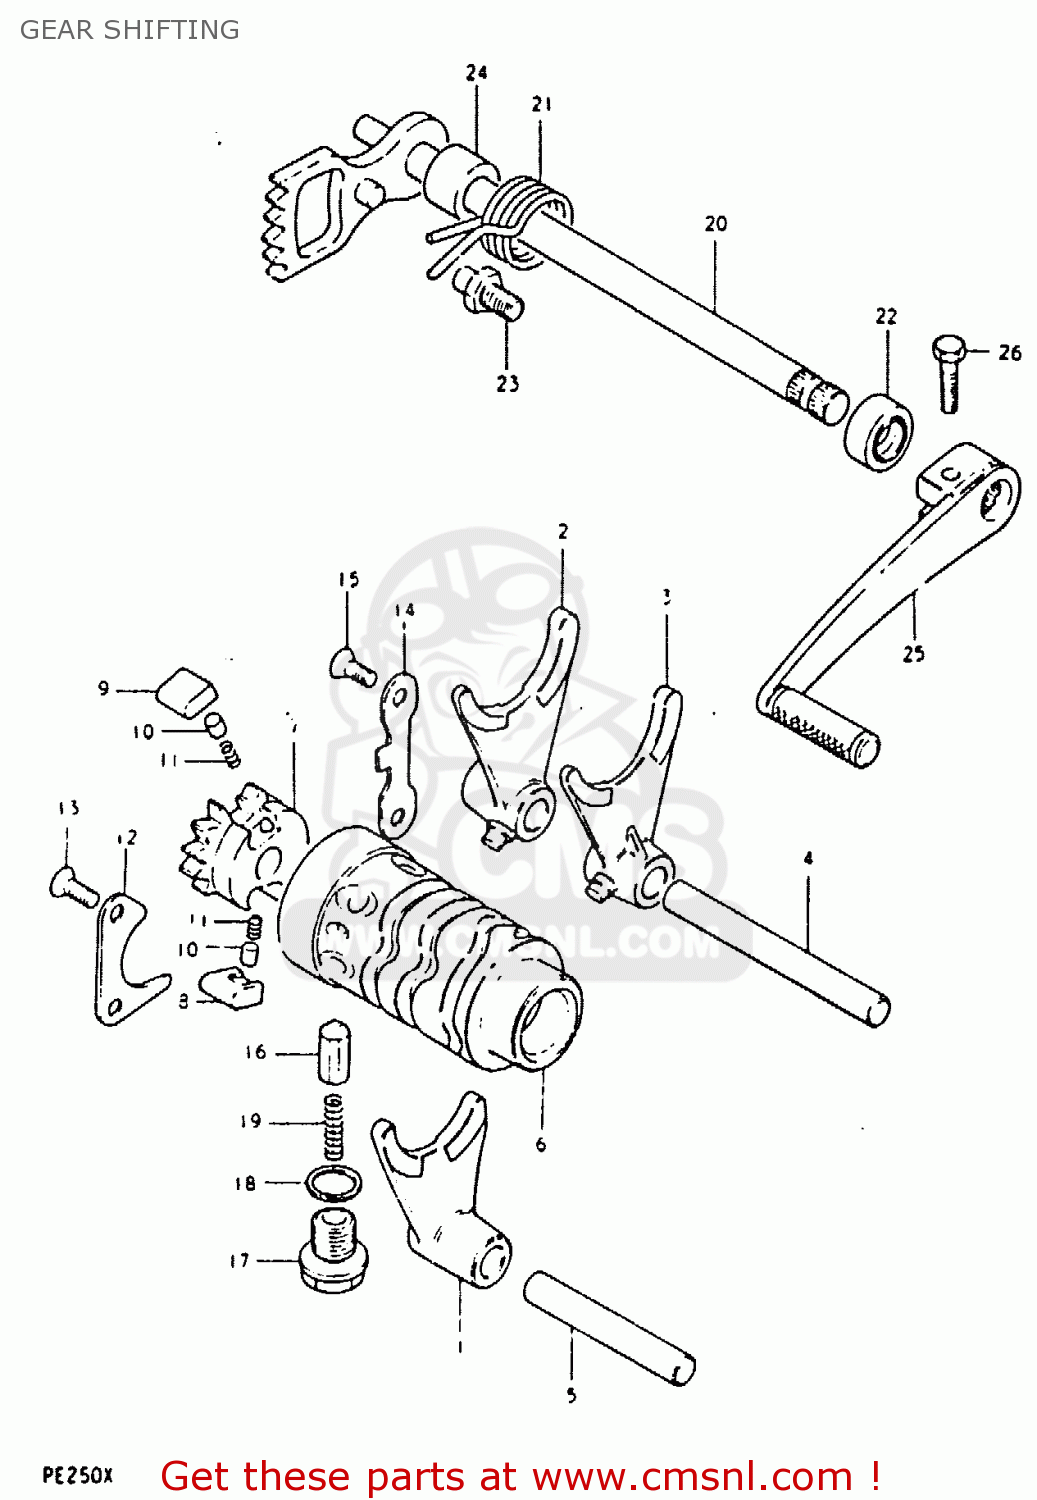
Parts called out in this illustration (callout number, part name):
1	FORK,GEAR SHIFT NO.1
2	FORK,GEAR SHIFT NO.2
3	FORK,GEAR SHIFT NO.3
4	SHAFT,GEAR SHIFT FORK
5	SHAFT,GEAR SHIFT FORK
6	CAM,GEAR SHIFT
7	RETAINER,GEAR SHIFT CAM
8	PAWL,GEAR SHIFT NO.1
9	PAWL,GEAR SHIFT NO.2
10	PIN(5X8)
11	SPRING
12	LIFTER,GEAR SHIFT PAWL
13	SCREW
14	GUIDE,GEAR SHIFT CAM
15	SCREW
16	STOPPER,GEAR SHIFTING
17	BOLT,GEAR SHAFT CAM STOPPER
18	GASKET(14X19.2X2) (NAS)
19	SPRING
20	SHAFT,GEAR SHIFT
21	SPRING
22	OIL SEAL
23	STOPPER,GEAR SHIFT CAM
24	SPACER(12X20X15.3)
25	LEVER ASSEMBLY,GEAR SHIFTING
26	BOLT
